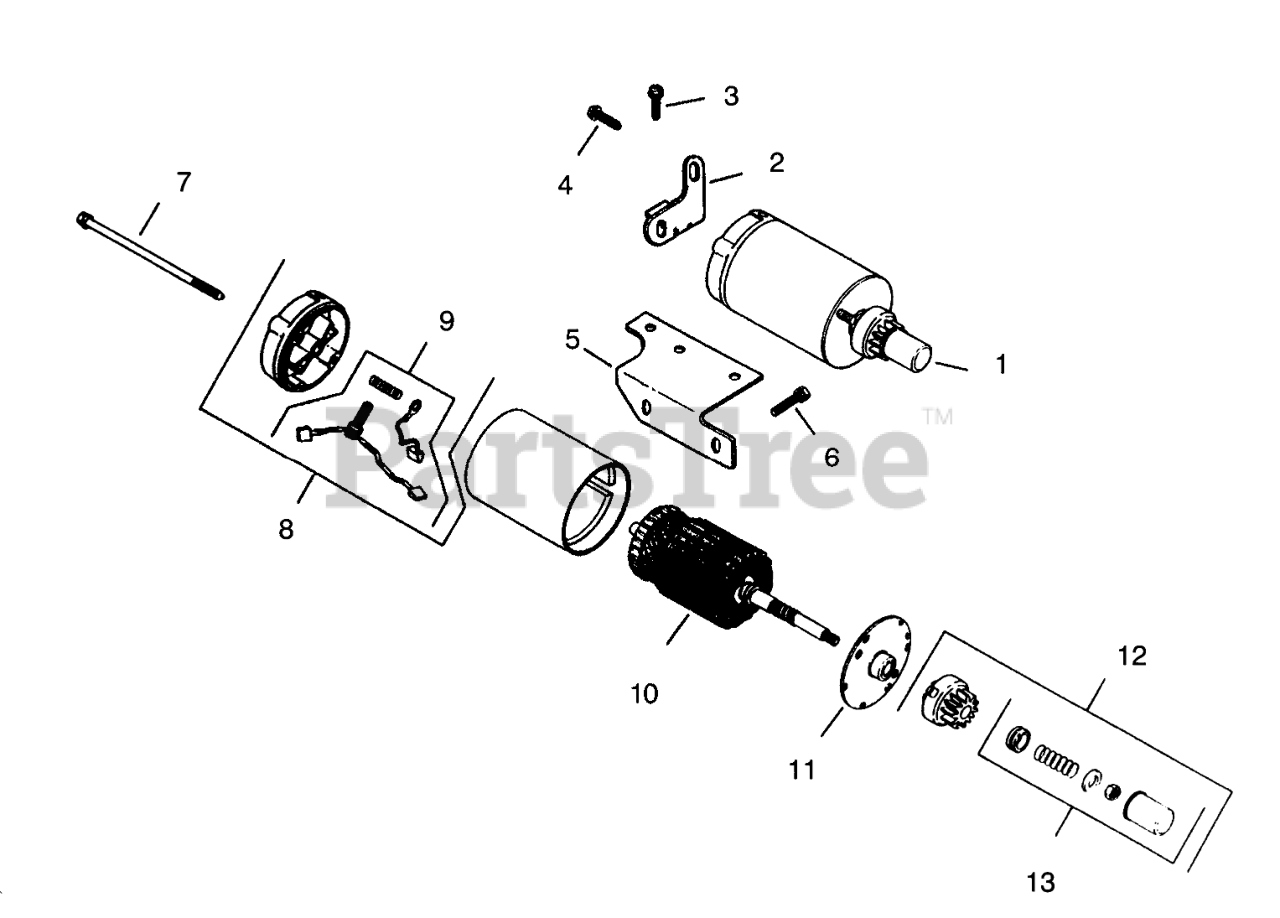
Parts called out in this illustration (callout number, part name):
1	Starter Assembly (Includes Items 9 thru 12)
2	Brace-Starter Tail
3	Screw-Hex. Hd.
4	Screw
5	Bracket-Starter
6	Screw
8	End Cap Ass-y (Incl. Ref. #9)
9	Brush Kit
10	Armature
11	Cap-Drive End
12	Kit-Drive (Incl. Ref. #15)
13	Drive Parts Kit
